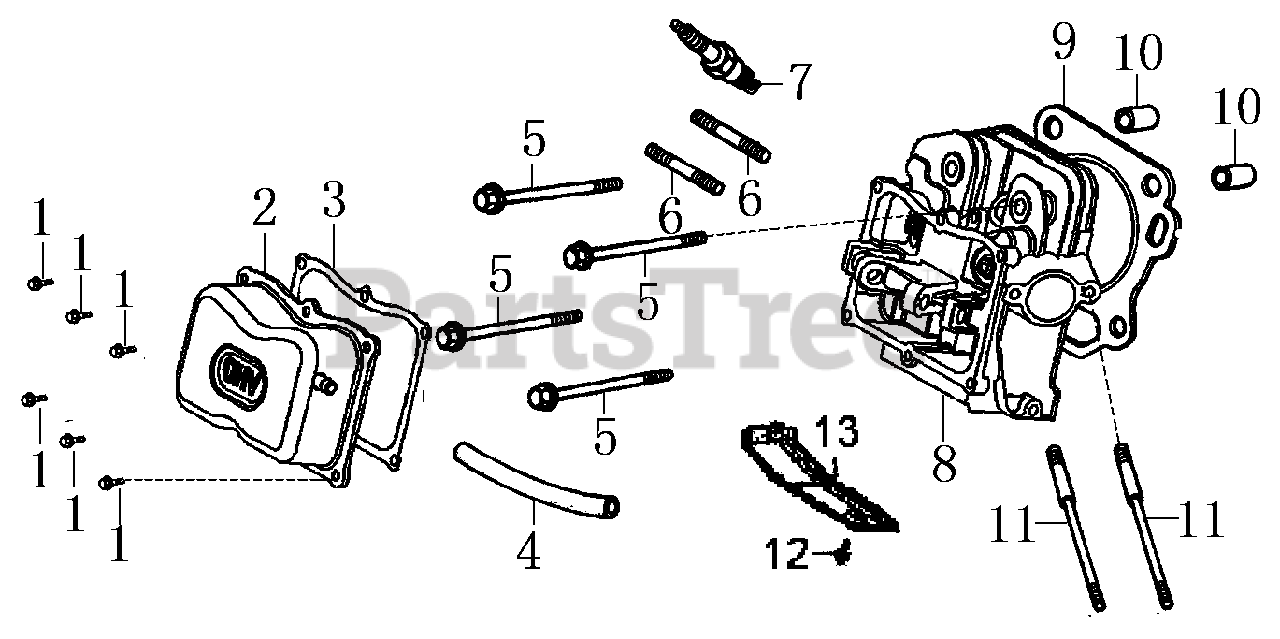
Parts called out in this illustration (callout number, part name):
1	BOLT, FLANGE
2	COVER, HEAD
3	GASKET, HEAD COVER
4	TUBE, BREATHER
5	BOLT, FLANGE, 10×80
6	BOLT, STUD, EXHAUST
7	SPARK PLUG
8	CYLINDER HEAD
9	GASKET, CYLINDER
11	BOLT, STUD, INTAKE
12	BOLT, FLANGE M6×12
